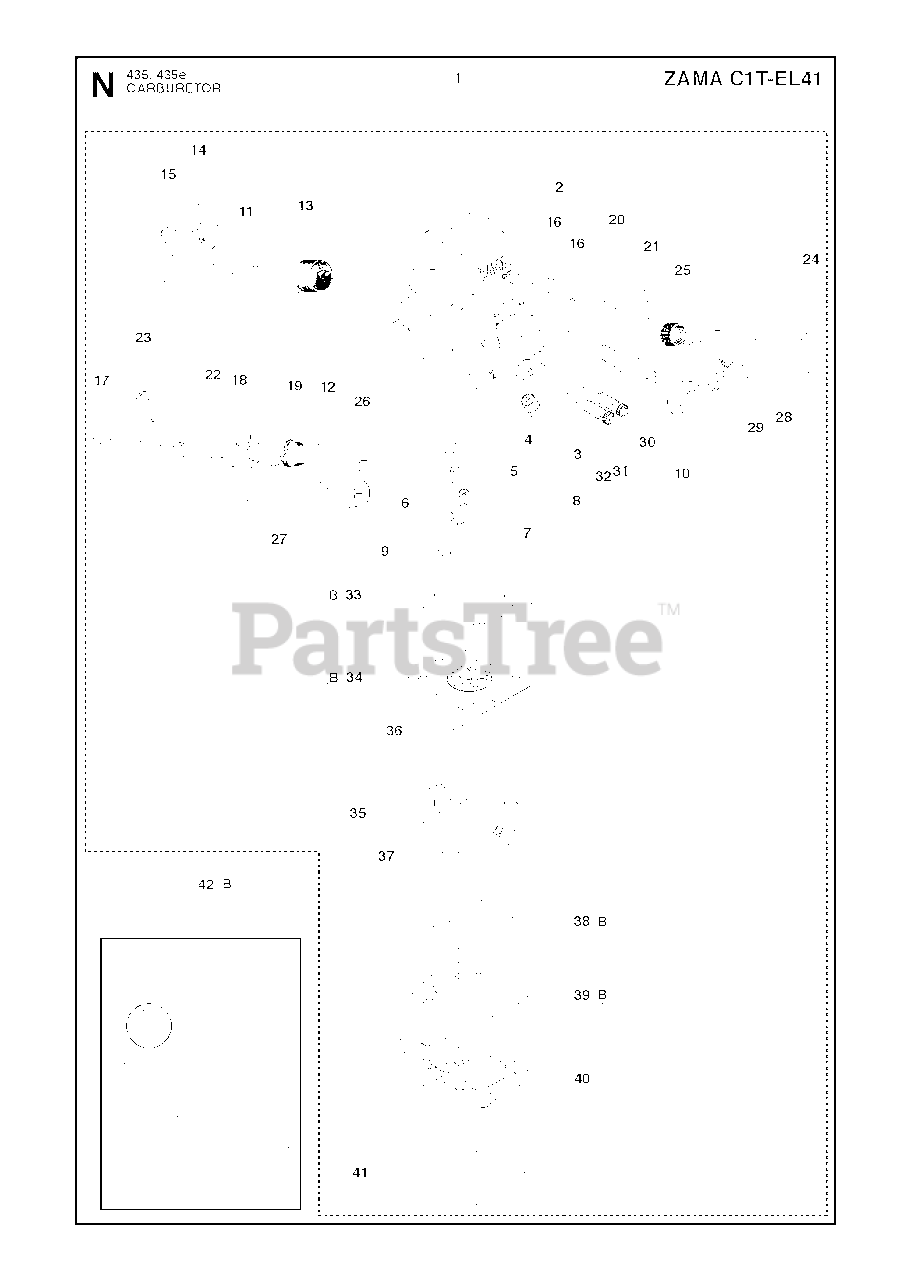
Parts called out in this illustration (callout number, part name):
1	CARBURETOR
2	PLUG
3	NOZZLE ASSY
4	PLUG
5	INLET NEEDLE
6	SPRING
7	LEVER
8	PIN FULCRUM
9	SCREW
10	CAP ZAMA 0051034
11	SHAFT ASSY
12	COLLAR ZAMA 005020
13	SPRING
14	VALVE
15	SCREW
16	CIRCLIP
17	SHAFT ASSY
18	LEVER
19	SPRING
20	LEVER
21	SCREW
22	VALVE
23	SCREW
24	SHAFT ASSY
25	SPRING
26	LEVER
27	SCREW
28	VALVE
29	SCREW
30	SCREW
31	SCREW
32	SCREW
33	GASKET
34	DIAPHRAGM
35	BODY
36	Screw
37	STRAINER
38	DIAPHRAGM
39	GASKET
40	COVER
41	Screw
42	GASKET KIT
